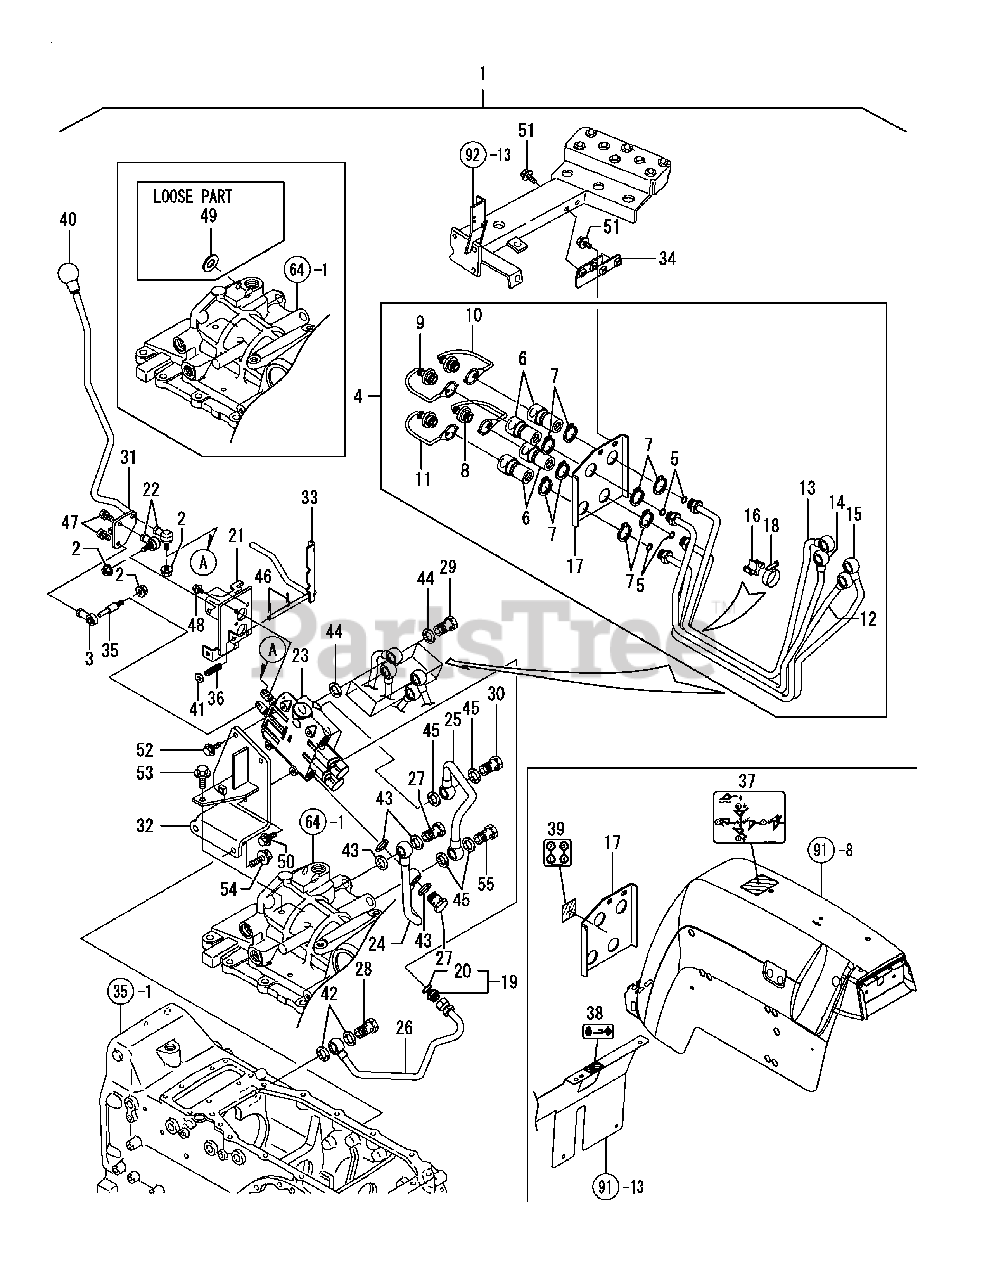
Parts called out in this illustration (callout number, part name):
2	NUT W/WASHER 8
6	COUPLER,QUICK 3/8F
8	PLUG, DUST RED
9	PLUG, DUST BLUE
10	PLUG, DUST YELLOW
11	PLUG, DUST GREEN
17	SUPPORT,SCV COUPLER
19	CONNECTOR,3/4UNF-3/8
21	BKT CMP,SCV LEVER
24	HP PIPE,SCV PUMP
25	HP PIPE,SCV PBYD
26	LINE,SCV DRAINT
33	PLATE CMP,LOCK
34	BKT,SCV SUPPORT
35	BOLT,SCV LEVER
37	LABEL,SCV LEVER
38	LABEL,SCV LOCK
39	LABEL,SCV COUPLER
46	COTTER PIN 2.5X30
47	BOLT W/WASHER M8X16
48	BOLT M 6X 16 PLATED
50	BOLT M 8X 16 PLATED
51	BOLT M 8X 20 PLATED
52	BOLT M 8X 20 PLATED
53	BOLT M10X 20 PLATED
54	BOLT M10X 25 PLATED
